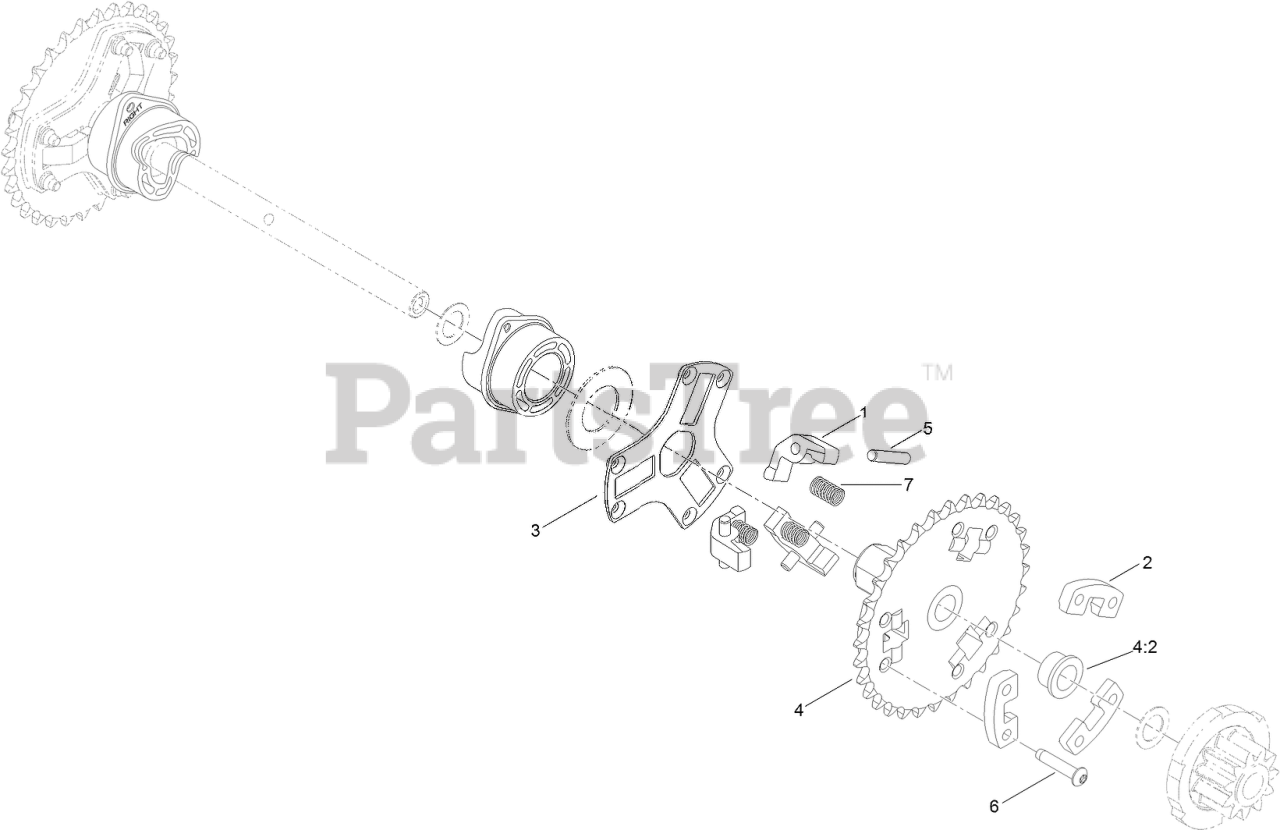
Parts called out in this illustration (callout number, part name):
1	PAWL-CLUTCH
2	SUPPORT-PAWL
3	RETAINER-PIN, PAWL
4	32T SPROCKET ASM
4:2	BUSHING-FLANGE
5	PIN-DOWEL
6	SCREW-TTH, THREAD ROLLING
7	SPRING-COMPRESSION
